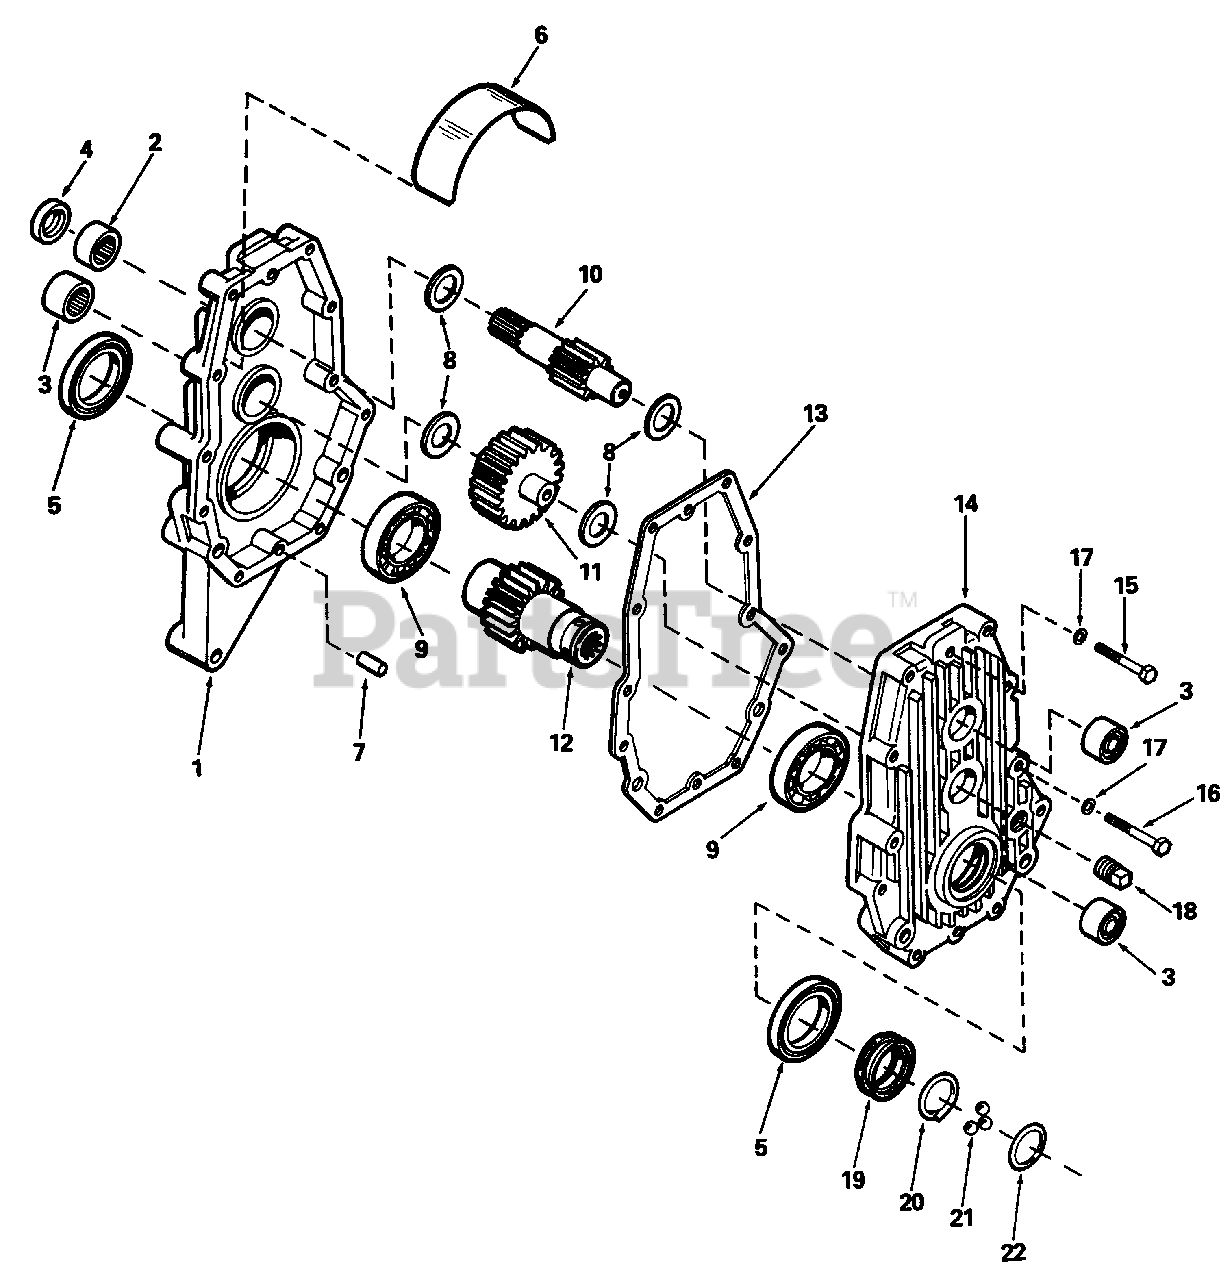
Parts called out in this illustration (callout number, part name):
1	CASE ASSY.
2	BEARING, Cartridge
3	BEARING, Cartridge
4	SEAL, Oil
5	SEAL, Oil
7	PIN, Dowel
8	WASHER, Thrust
9	BEARING, Ball
10	PINION, Input
11	GEAR, Idler
12	SHAFT, Output
14	COVER ASSY.
15	SCREW, Hex Hd., 5/16-18 x 1-3/4
16	SCREW, Hex Hd., 5/16-18 x 2
17	LOCKWASHER, 5/16
18	PLUG, Magnetic Drain
20	RING, Retaining
21	BALL, Steel, 3/8
22	RING, Retaining
